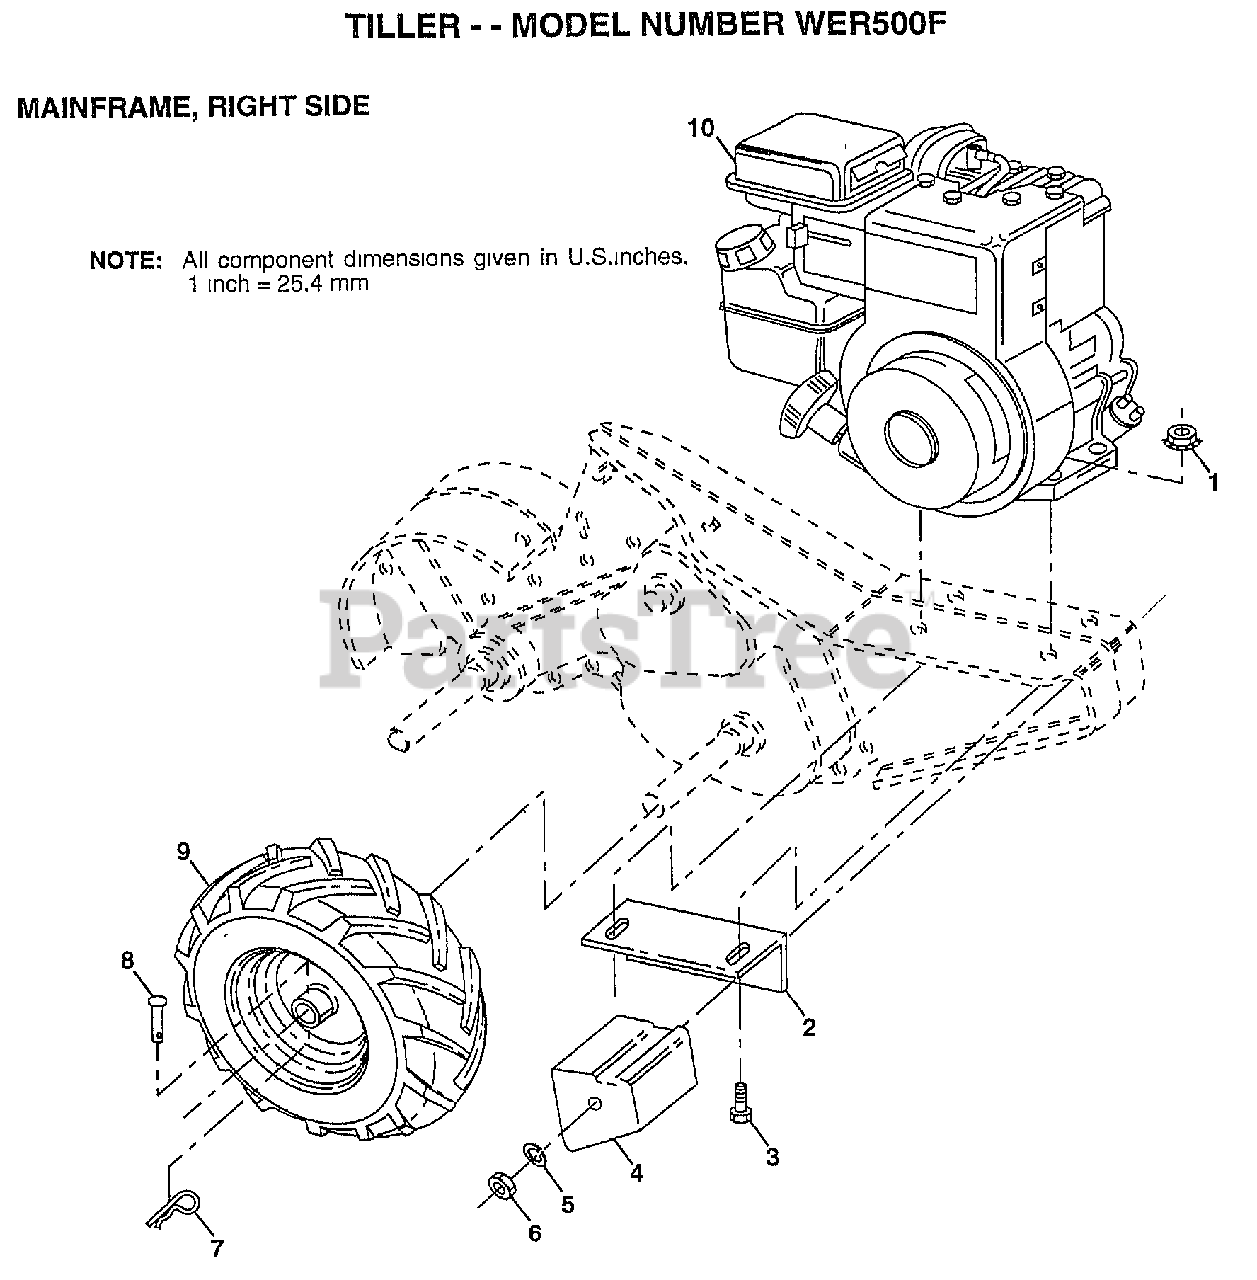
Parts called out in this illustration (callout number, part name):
2	BRACKET RH CRT
3	BOLT.HEX.5/16-1.5
4	COUNTERWEIGHT CRT
5	LOCKWASHER
6	NUT.HEX.3/8-16UNC
7	RETAINER M
8	RIVET.DRILL.1.75
9	TIRE.CHV.13X5.0-6
10	ENGINE, B&S
